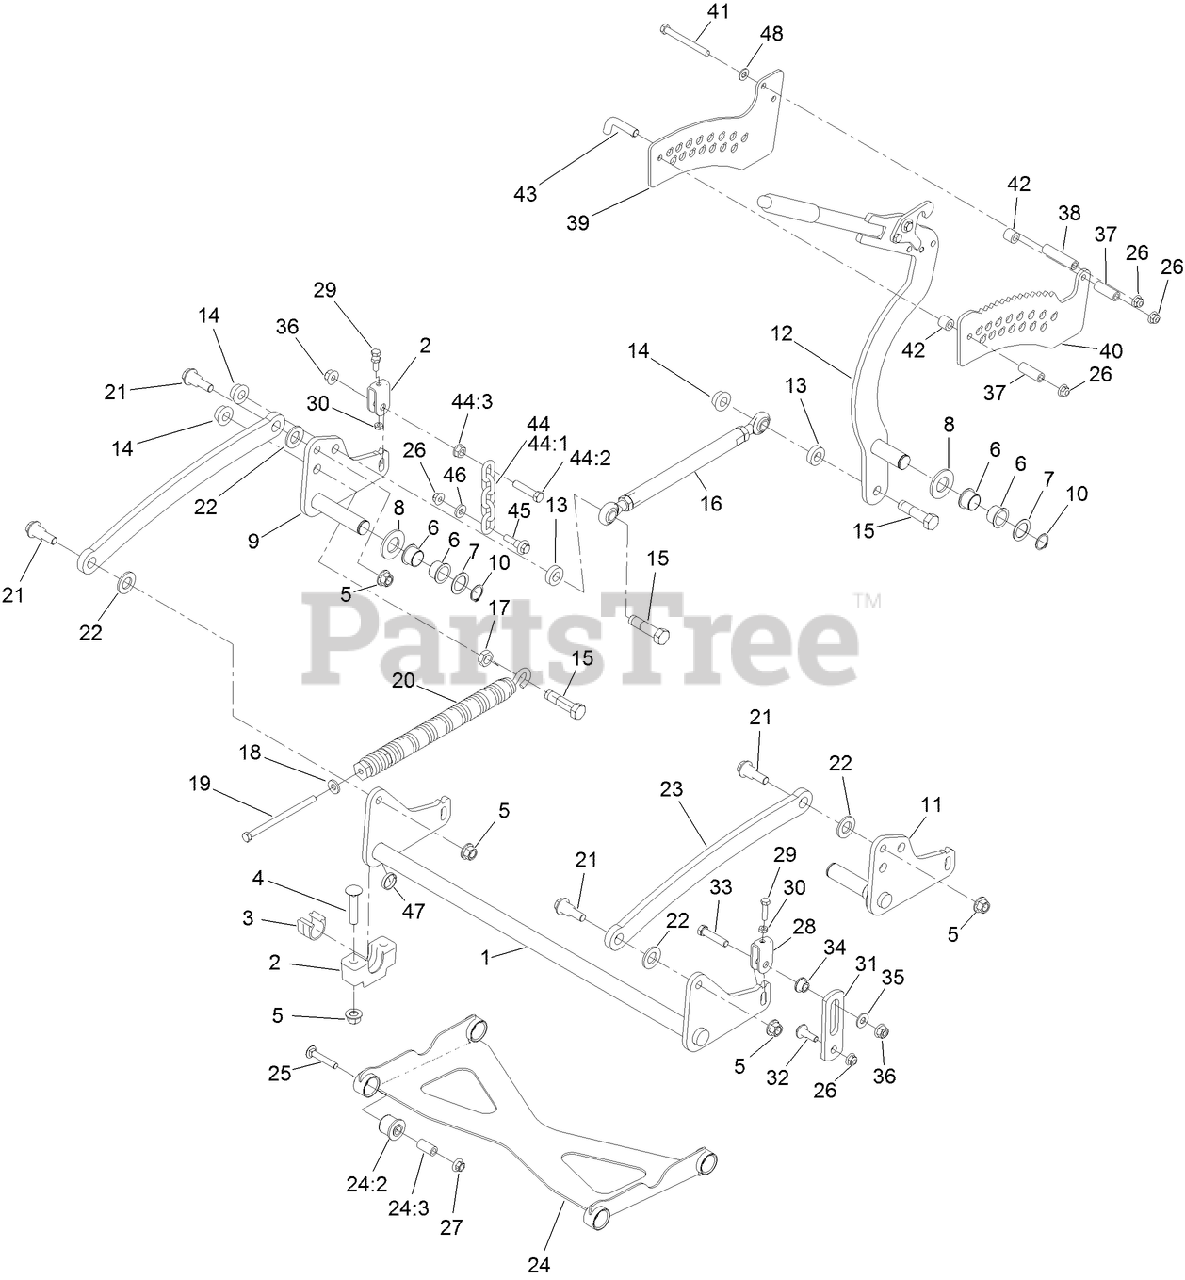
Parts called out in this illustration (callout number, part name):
1	SHAFT-CROSS, FRONT
2	SUPPORT-CROSS SHAFT, BEARING
3	BEARING-CROSS SHAFT, FRONT
4	BOLT-CARR
5	NUT-LOCK
6	BUSHING
7	WASHER-THRUST
8	WASHER-FLAT
9	ARM-LIFT, REAR (RH)
10	RING-RETAINING
11	ARM-LIFT, REAR (LH)
12	HOC LEVER ASM
13	WASHER
14	NUT-HEX FLG
15	SCREW-LOCK
16	HOC LINK ASM
17	NUT-JAM
18	WASHER-BELLEVILLE
19	BOLT-TAP, HH
20	SPRING-EXTENSION
21	SCREW-SHOULDER, HHF
22	WASHER-FLAT
23	LINK-LIFT
24	DECK STRUT ASM
24:2	BUSHING-RUBBER
24:3	SPACER
25	SCREW-CARR
26	NUT-HF, NI
27	NUT-HF
28	YOKE-ADJUST, DECK
29	SCREW-HH
30	NUT-JAM
31	LINK-LIFT
32	SCREW-SHOULDER, HHF
33	SCREW-HH
34	BUSHING-FLANGED
35	WASHER-FLAT
36	NUT-HF, NI
37	SPACER
38	SPACER
39	HOC PLATE AND DECAL ASM
40	PLATE-HOC, INNER
41	SCREW-HH
42	SPACER
43	PIN-HOC
44	DECK LIFT CHAIN ASM
44:1	CHAIN-LIFT, DECK
44:2	SCREW-HH
44:3	NUT-HF
45	BOLT-SHOULDER
46	SPACER
47	SPACER-SPLIT
48	WASHER-FLAT
